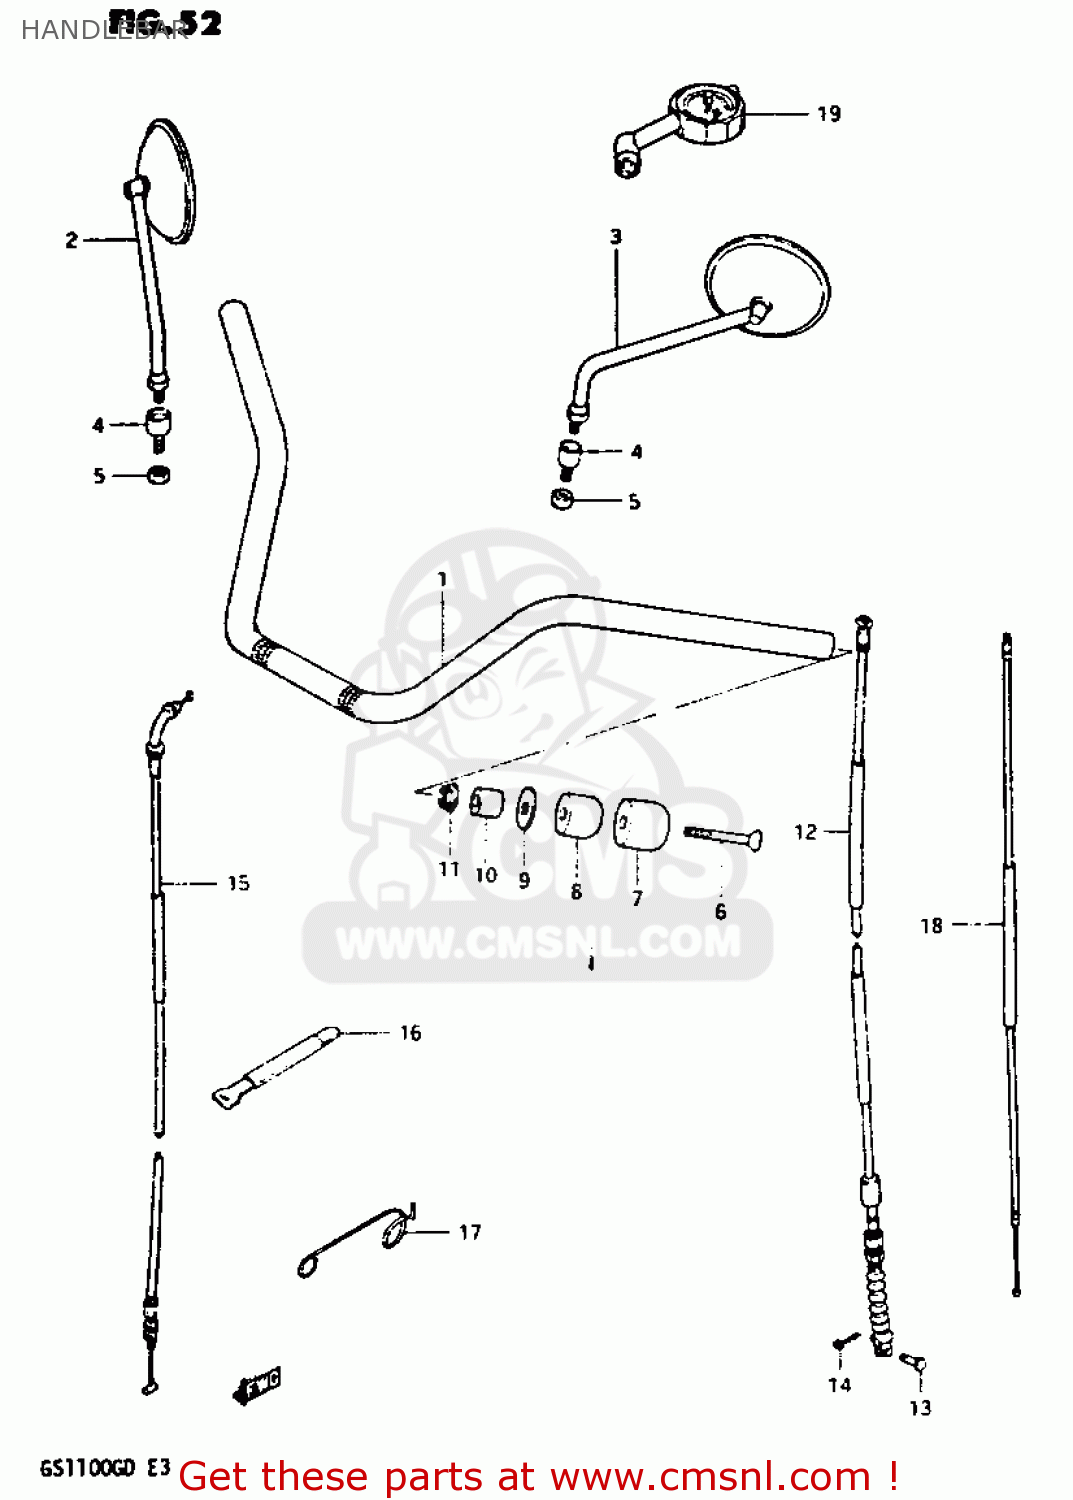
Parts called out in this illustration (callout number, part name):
1	HANDLEBAR
2	MIRROR ASSEMBLY,RIGHT
3	MIRROR ASSEMBLY,LEFT
4	CUSHION,REAR VIEW MIRROR
5	NUT
6	SCREW
7	CAP,BALANCER
8	BALANCER,HANDLE
9	SPACER,BALANCER
10	EXPANDER,HANDLE BALANCER
11	NUT
12	CABLE ASSY,CLUTCH
13	PIN(L:15)
14	PIN
15	CABLE ASSY,THROTTLE NO.1
16	CLAMP
17	GUIDE,CLUTCH CABLE
18	CABLE,STARTER
19	GAUGE ASSY,AIR PRESSURE
